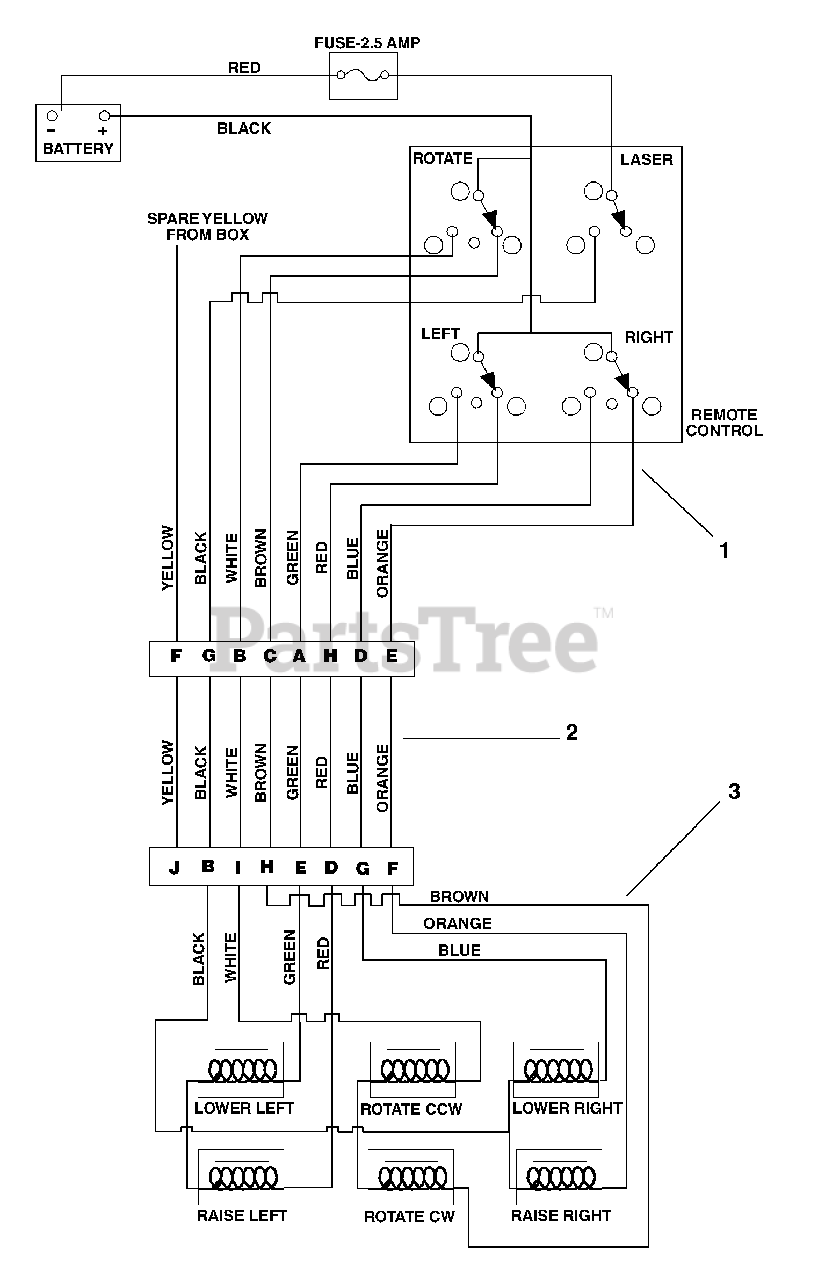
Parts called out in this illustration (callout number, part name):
1	Remote Control Harness
2	Valve Control Harness
3	Electric Valve Harness
